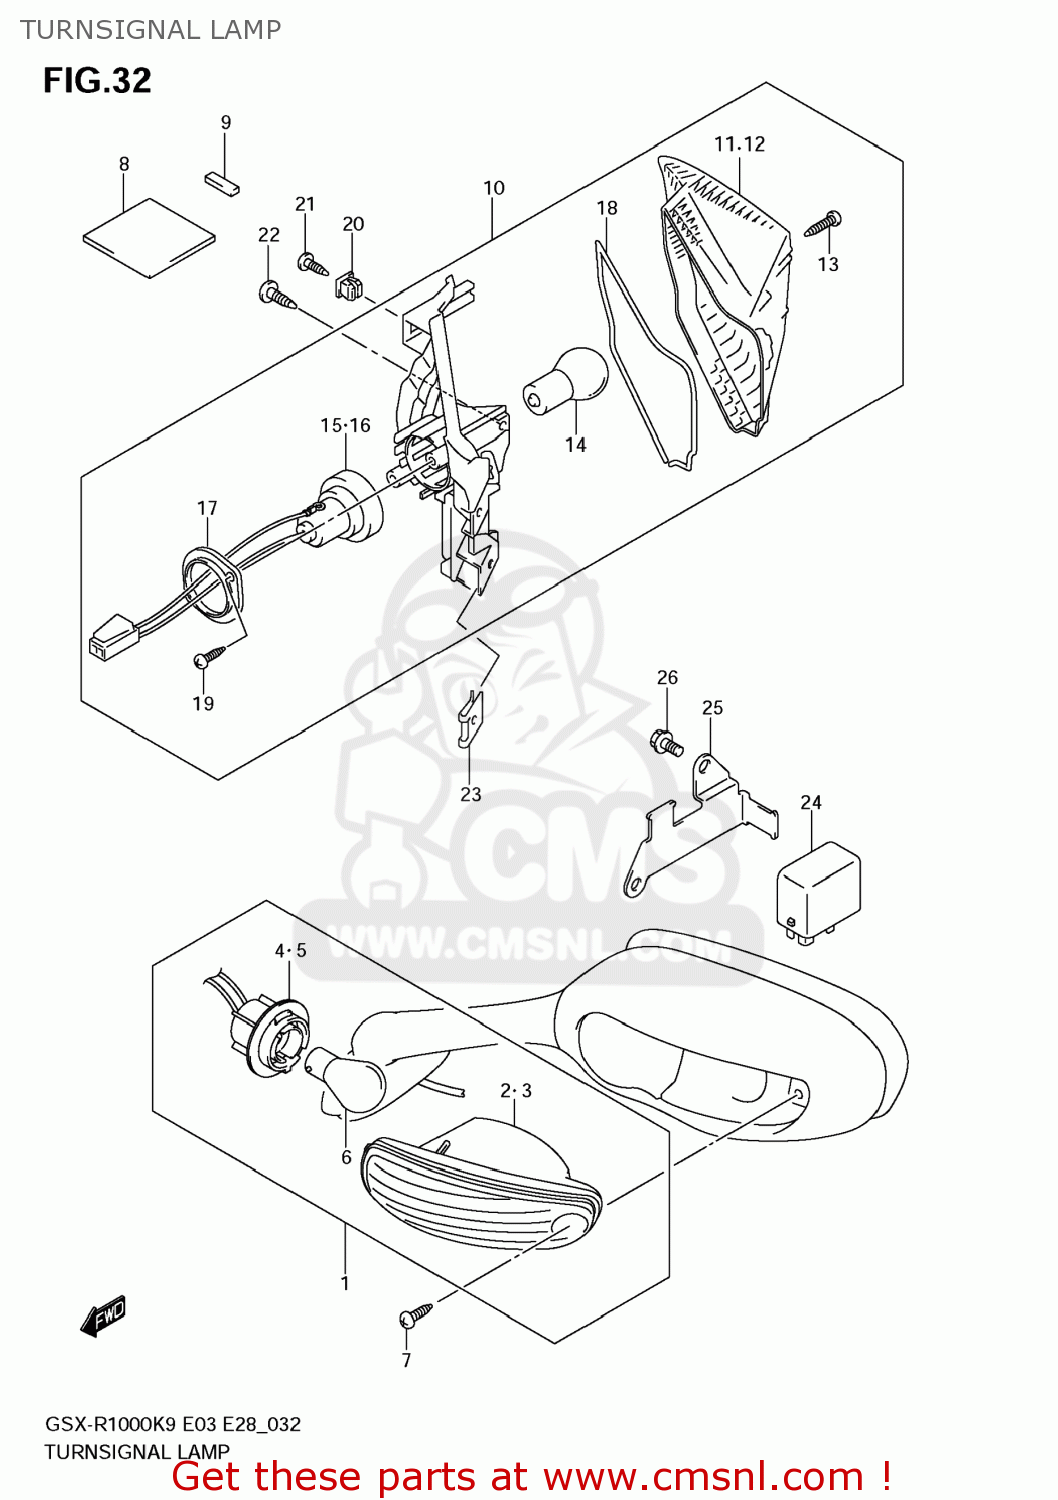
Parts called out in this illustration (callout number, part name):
1	LAMP ASSY,FR TURN SIGNAL,R
2	LAMP UNIT,R
3	LAMP UNIT,L
4	SOCKET,R
5	SOCKET,L
6	BULB(12V21W,AMBER)
7	SCREW(4X20)
8	CUSHION(40X20X5)
9	TAPE,FR TURNSIGNAL
10	LAMP ASSY,RR TURNSIGNAL,R
11	LENS,R
12	LENS,L
13	SCREW
14	BULB(12V21W,AMBER)
15	SOCKET & CORD,R
16	SOCKET & CORD,L
17	PLATE,RR COMBINATION
18	GASKET (NAS)
19	SCREW
20	NUT
21	SCREW
22	SCREW
23	NUT
24	RELAY ASSY,TURNSIGNAL LAMP
25	BRACKET,RELAY
26	BOLT
